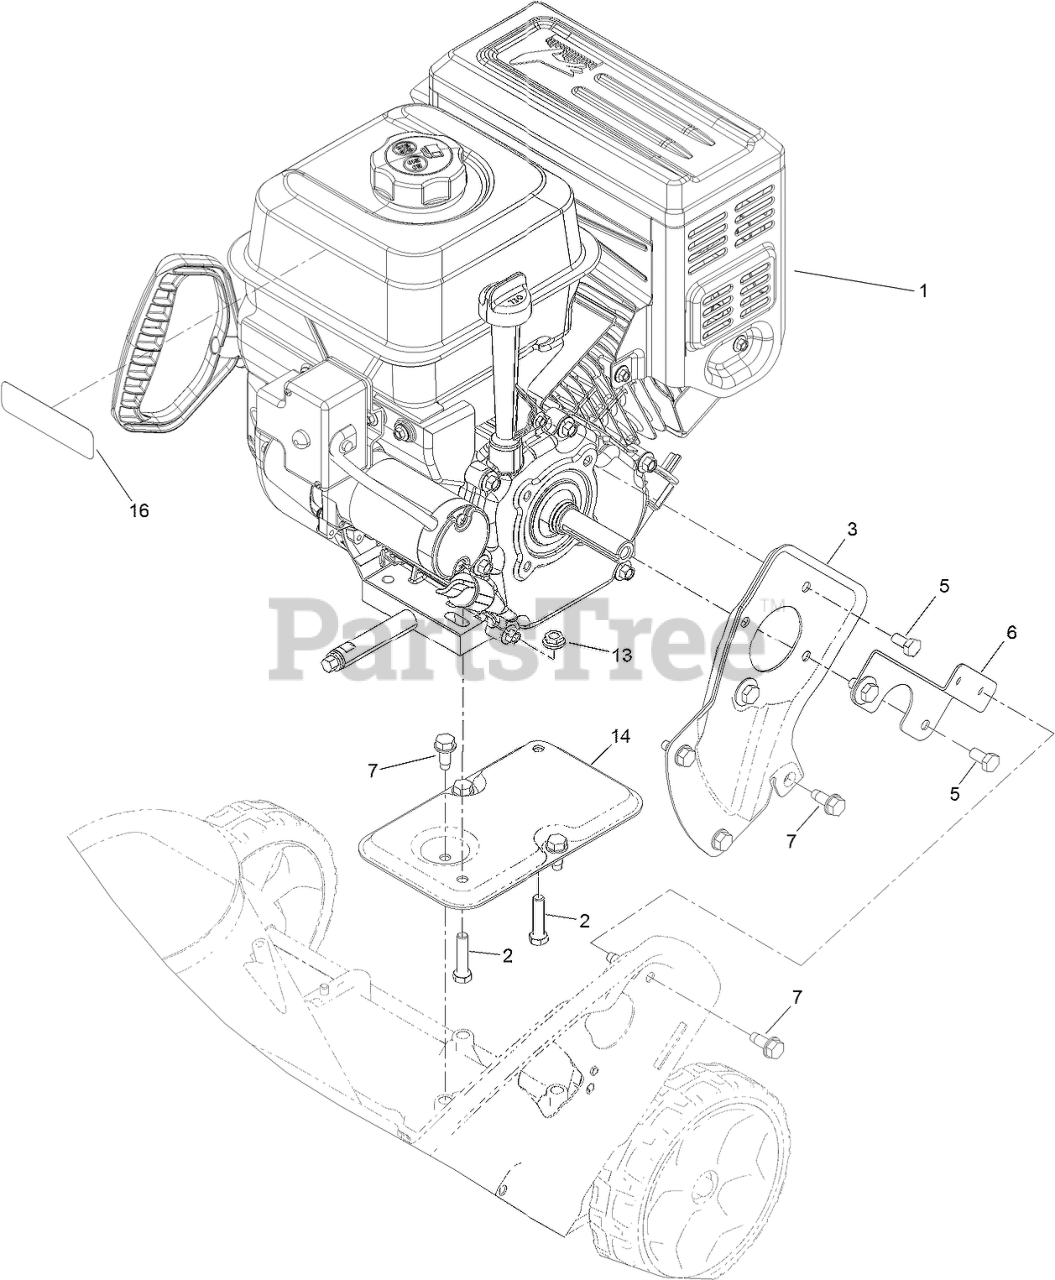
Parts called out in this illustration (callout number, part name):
1	ENGINE-G250FS-4
2	SCREW-HH
3	PLATE-ENGINE, PTO
5	BOLT
6	SUPPORT-ENGINE, SIDE
7	SCREW-THD ROLL, HWH
13	NUT-HF
14	SUPPORT-ENGINE
16	DECAL-ENGINE
